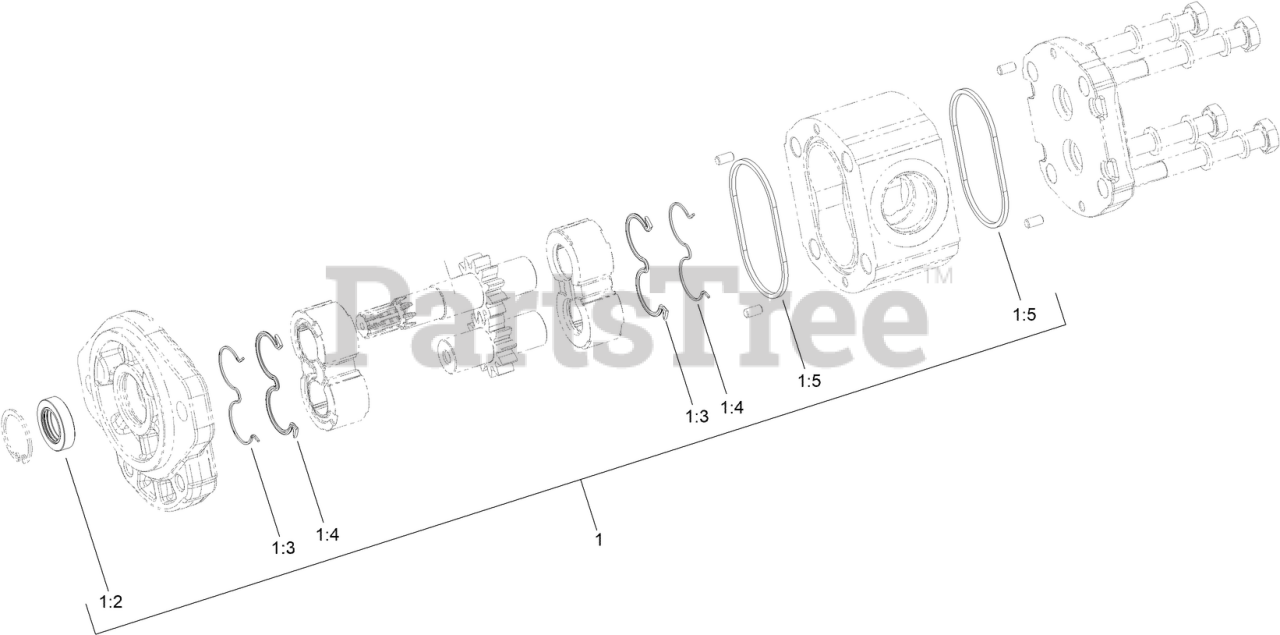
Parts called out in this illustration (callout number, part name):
1	KIT-SEAL
1:2	SHAFT SEAL
1:3	ANTI-EXTRUSION SEAL
1:4	SEAL
1:5	SEAL SQUARE SECTION
